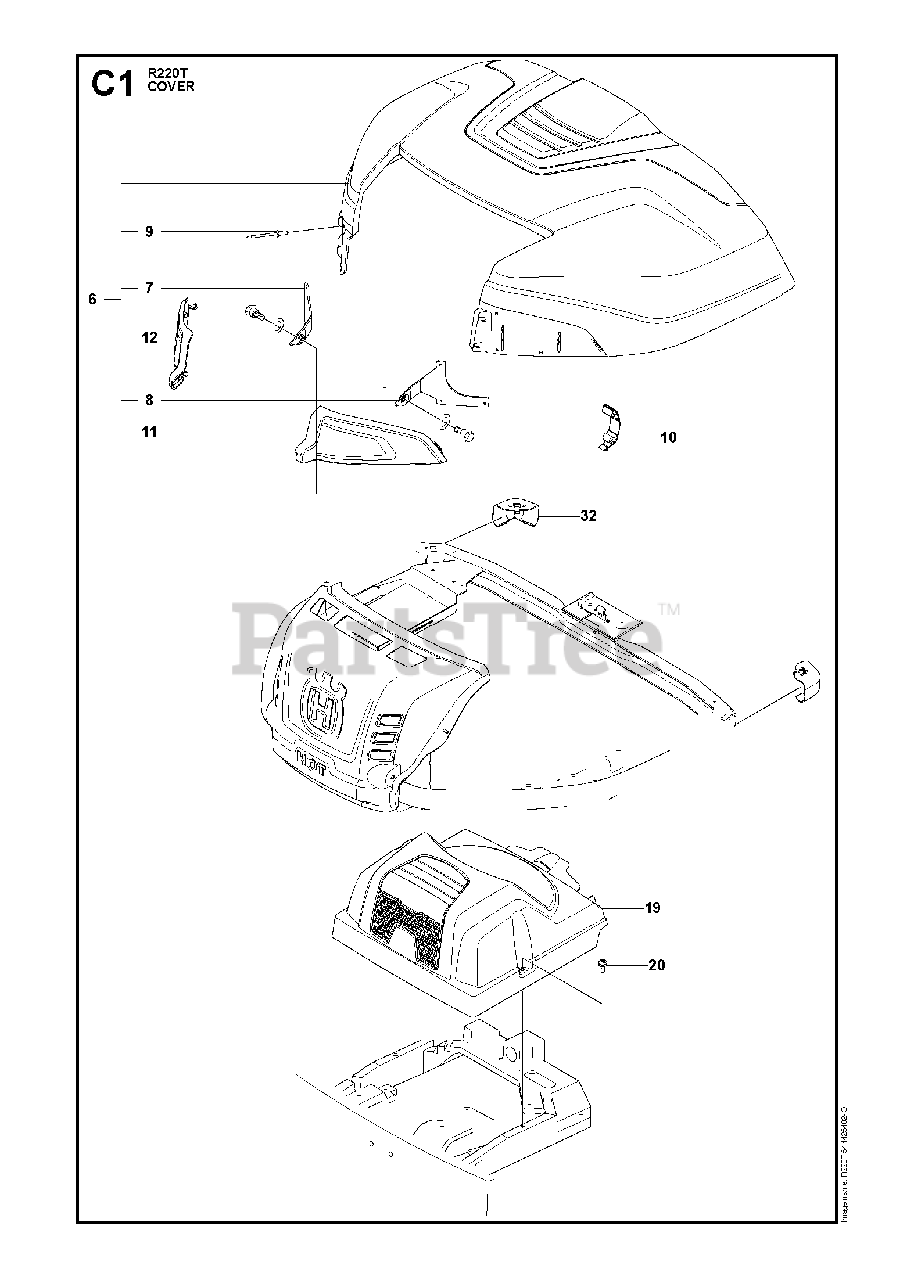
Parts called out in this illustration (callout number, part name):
6	ENGINE HOOD ASSY
10	CLIP GRAY
19	TRANSMISSION COVER
